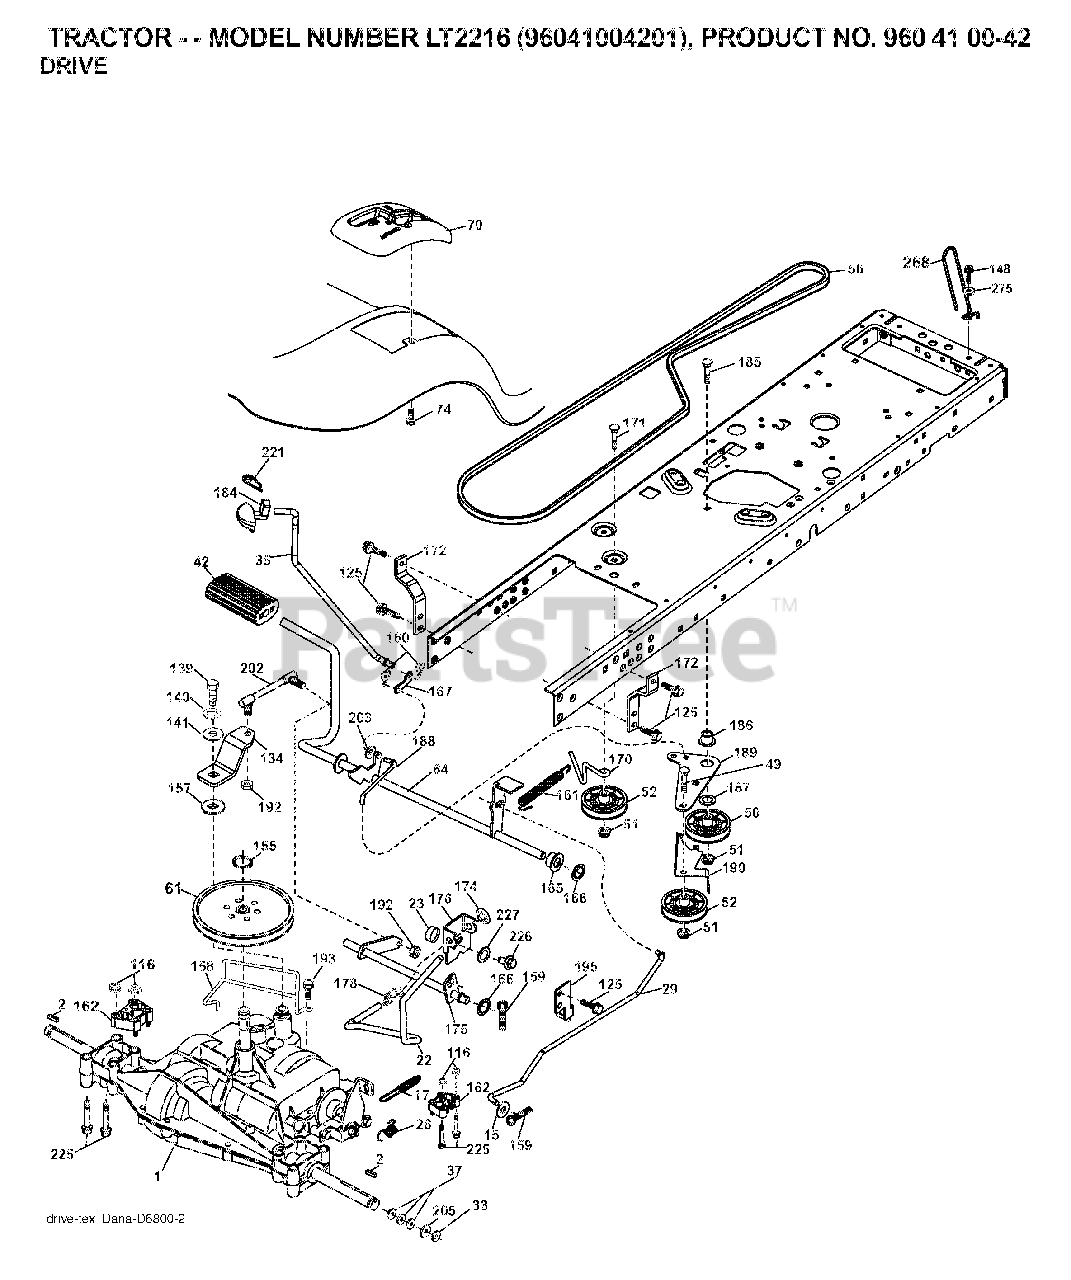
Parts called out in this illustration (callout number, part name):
2	SQUARE KEY
17	SPRING.BRAKE.PEERLESS.TEX
22	ROD.SHIFT.FENDER.TLT.2006
23	KNOB.DUCKHEAD.1/2
26	SPRING.BRAKE.RTN.GR.DR
29	ROD.BRAKE.PEERLESS
33	E-RING LT
35	ROD.BRAKE.PARKING.LT.T
42	PEDAL COVER T
49	BOLT
50	IDLER.FLAT.910.OFFSET
51	NUT LOCK FLG 3/8-16 UNC
52	IDLER.V-GROOVE.1.688.OFFSET
56	V-BELT.TRACTOR.DRIVE.P
61	PULLEY TRANS
64	SHAFT.ASM.PEDAL.BRAKE.
74	SCREW.HI-LO.CONSOLE
116	NUT LOCK HEX FLANGE 5/16-18
125	SCREW
134	ARM.SHIFT.
139	BOLT 1/4-28X3/4
140	LOCKWASHER
141	WASHER LT
148	SCREW, 3/8-16X3/4
155	RETAINING RING LT
157	WASH-SHFT PLT LT
158	KEEPER.PMS.18/20.D4365
159	COTTER PIN
160	RETAINER CLIP
161	SPRING.RETURN.CLUTCH.2006
162	SPACER.TRANSAXLE.18&22
165	BUSHING.SHAFT.BRAKE.HAND
166	NUT.PUSH.625.2006
167	LATCH.BRAKE.SPRING
170	KEEPER.V-IDLER.CENTER.
172	STRAP.TRQ.LH.GEAR.DRIV
174	NUT.PUSH.500.2006
175	SHAFT.ASM.SHIFT.
176	ARM.CLEVIS.ROD.SHIFT
178	SPRING.SHIFT.GT2006
184	HANDLE.PAKRING.BRAKE.
186	SPACER.RETAINER
187	WASHER 12/32X2X10GA
188	LINK.CLUTCH.GROUND.DRIVE
189	BELLCRANK.GROUND.DRIVE.TEX.
190	KEEPER.BELLCRANK.DRIVE
192	NUT LOCK CENTER 1/4 -28 FNTHD
193	SCREW 5/16"
195	BRKT.ROD.BRAKE.PEERLES
202	LINK.TRANSAXLE.
203	WASHER
221	RETAINER.SPRING.CLIP.H
225	BOLT.HEX.FLNG.5/16-18X3.75
226	BOLT FIN HEX 7/16-14 X 1
227	WASHER SERRATED
268	WASHER
